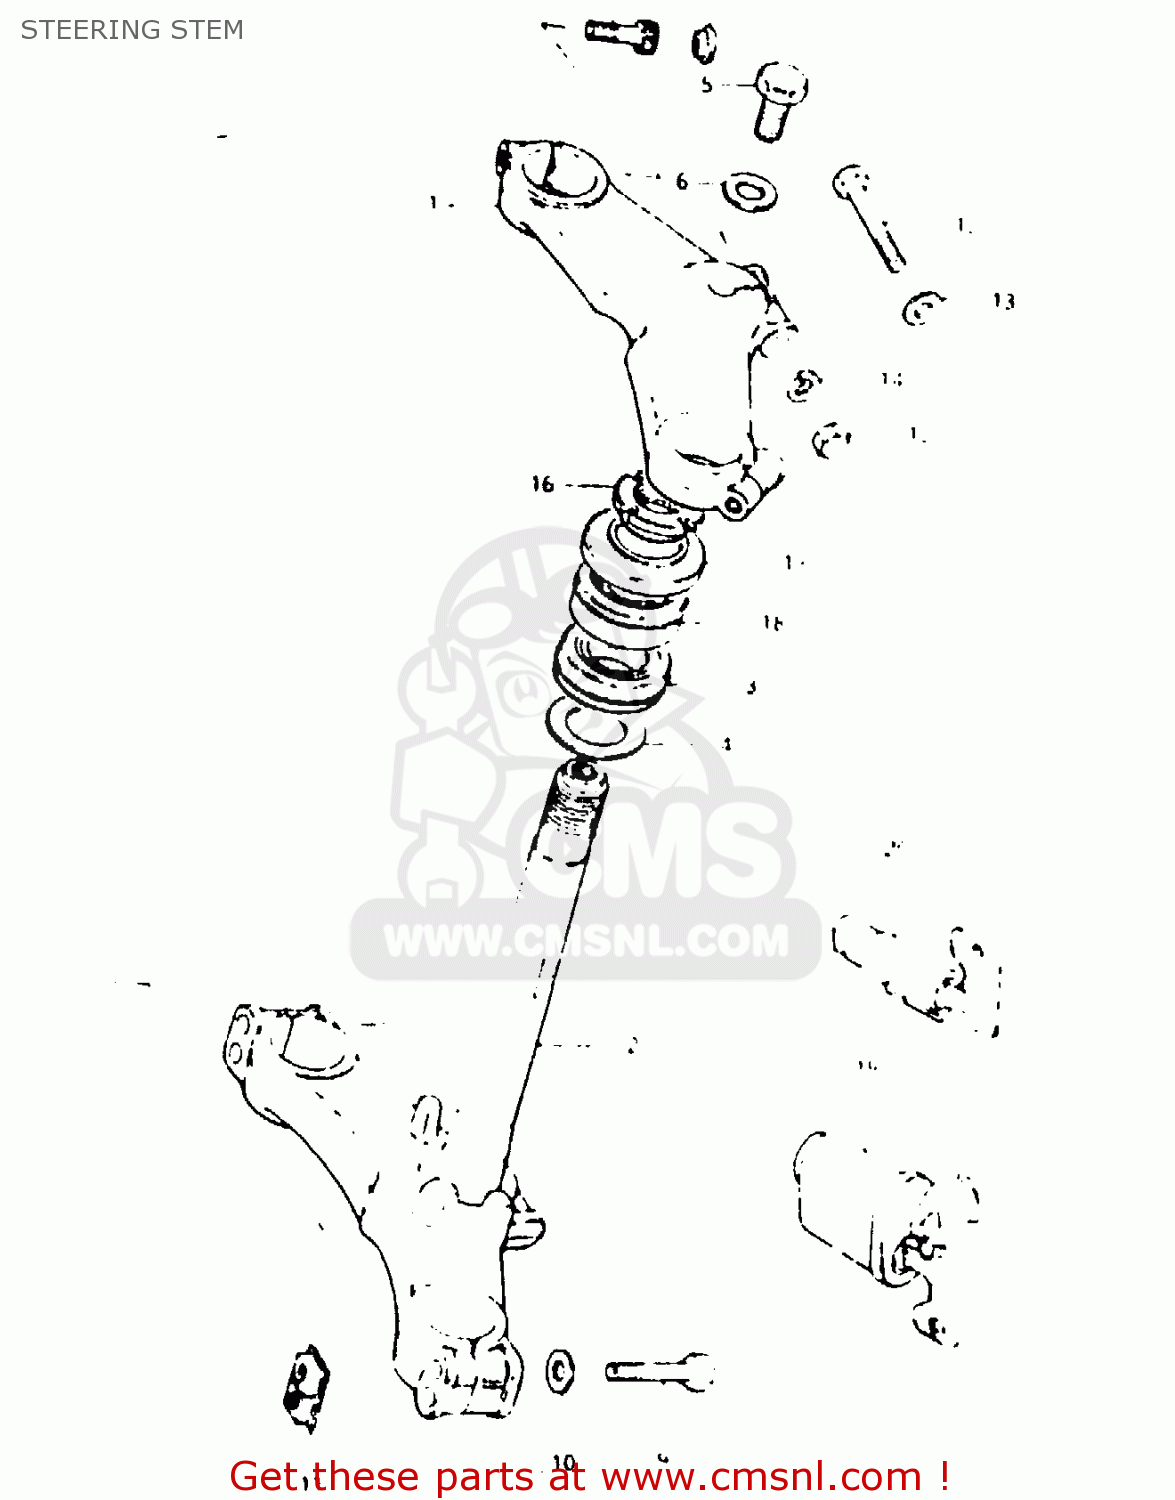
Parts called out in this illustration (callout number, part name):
1	STEM HEAD, STEERING (SILVER)
2	STEM, STEERING (SILVER)
3	BEARING
4	WASHER,THRUST
5	NUT,STEM HEAD
6	WASHER,STEERING STEM B
7	BOLT
8	CAP(OD:20)
9	BOLT 8X55
10	WASHER
11	NUT,FR FORK INNER TUBE
12	BOLT 8X50
13	WASHER
14	WASHER,LOCK,8.
15	NUT
16	NUT,STEERING STEM
17	DUST SEAL,STEERING UPR
18	TAPER,ROLLER BEARING
19	LOCK ASSEMBLY,STEERING (NEI
